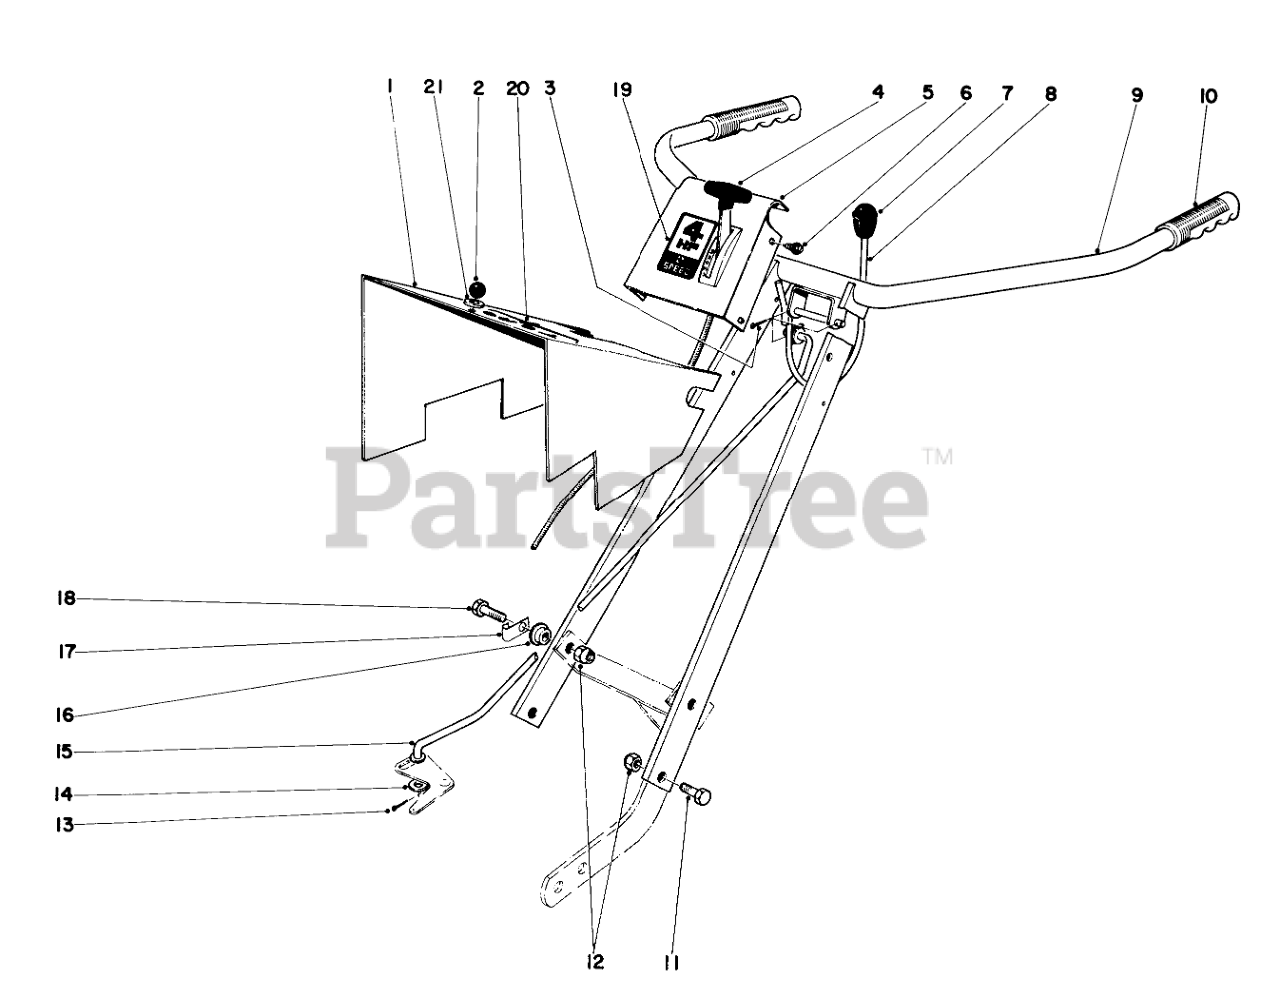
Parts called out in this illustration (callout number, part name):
1	Pulley Cover
3	PIN-COTTER
4	Throttle Assy.
5	Cover Handle
6	10-16 X 3/8 THDG SCREW
7	Knob
8	Shift Lever
9	Handle Bar
10	Handle Grip
11	SCREW-HH
12	NUT-LOCK, CONE
13	PIN-COTTER
14	Washer
15	Clutch Rod
16	Spacer
18	SCREW-HH
19	Decal
20	Decal
21	WASHER-FLAT
